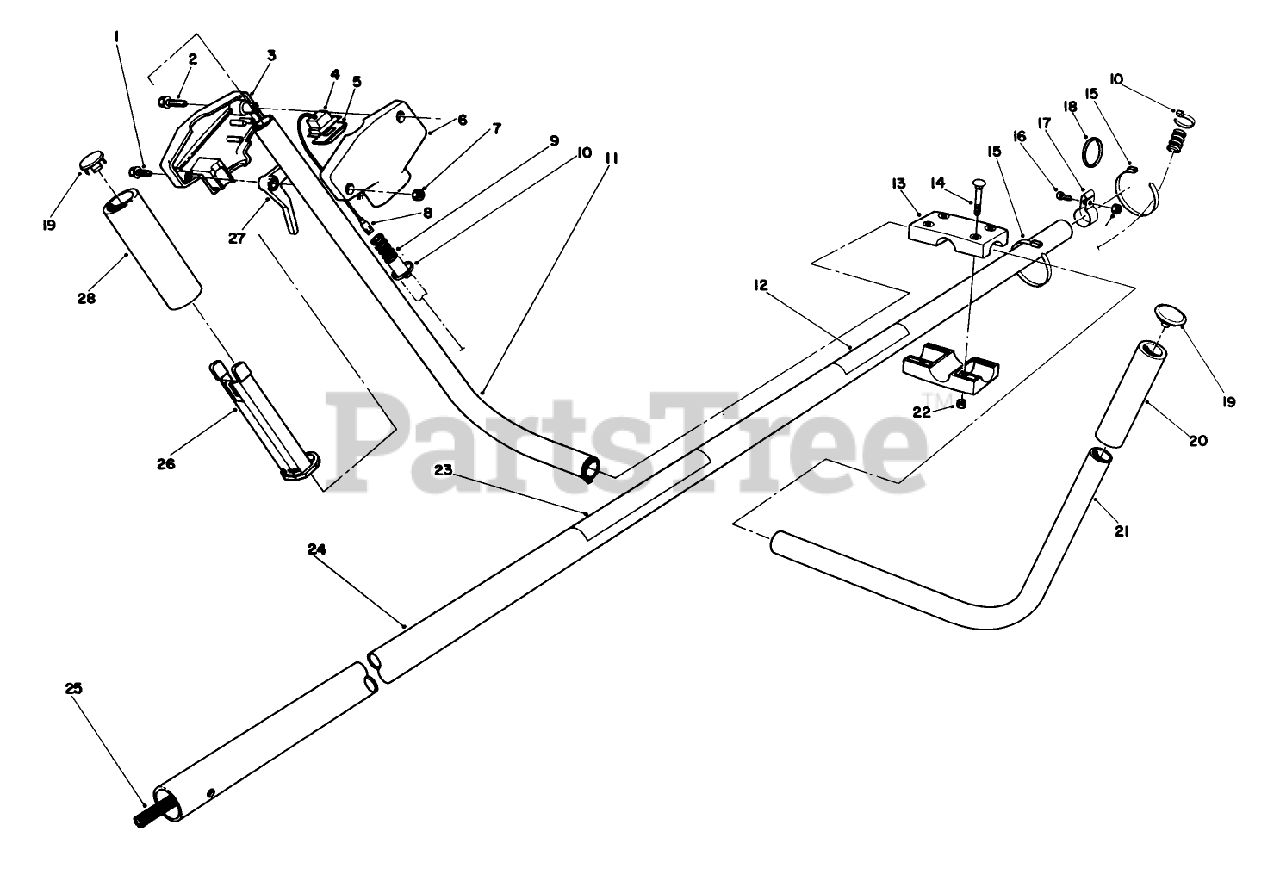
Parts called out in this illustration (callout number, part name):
1	SCREW-HWH
3	THROTTLE HSG R H 1"
4	SWITCH
6	THROTTLE HSG L H 1"
7	NUT-LOCK, NI
10	TIE-CABLE
15	TIE-CABLE
16	SCREW-SRH
17	HARNESS CLAMP
18	RING-HARNESS
21	LH HANDLE
22	NUT-LOCK, NI
26	TROUGH
28	GRIP-RUBBER
